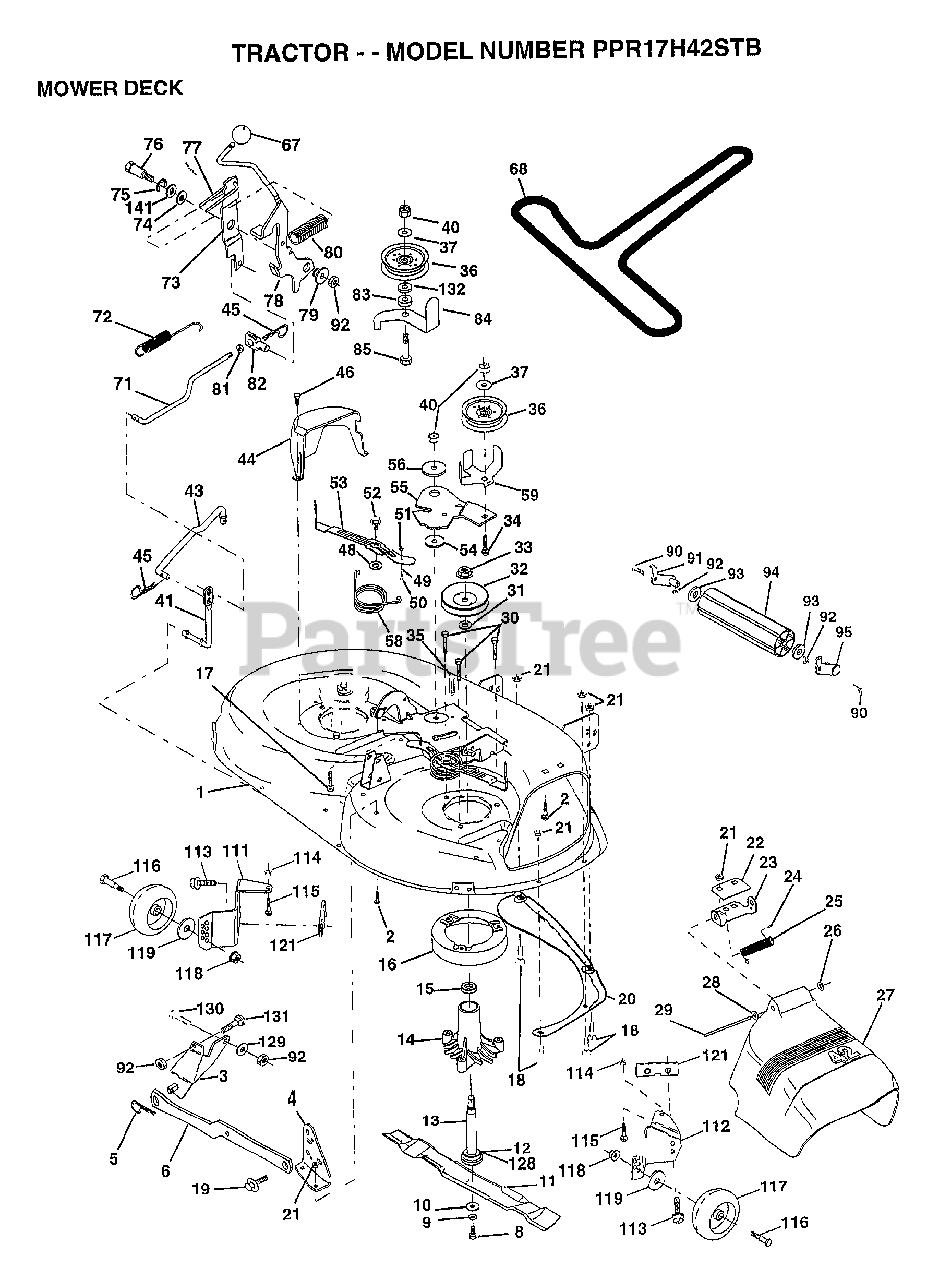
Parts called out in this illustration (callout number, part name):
1	"HOUSING ASSY.42"""
2	BOLT
3	BRKT ASM SWAY BAR
4	BRKT DECK SW BAR
8	BLADE BOLT
10	WASHER.HARD.BLADE
11	"BLADE.42"" HIPERF"
12	BEARING.BALL
14	HSG ASM MANDREL
15	BEARING
16	STRIPPER RND MWR
17	BOLT RDHD 3/8-16
18	BOLT
19	BOLT SHD 5/16-18
20	BAFFLE VORTEX 42
22	STIFFENER BRKT
23	DEFLECTOR BRKT
24	CAP-SLEEVE LT
25	SPRING TORSION
26	NUT PUSH M
27	DEFLECTOR.SHIELD
28	WASHER
29	HINGE ROD
30	"SCREW-THD ROLL,WA"
31	WASHER
32	PULLEY.MANDREL.42
34	BOLT
35	XMAS TREE FASTNER
36	FLAT IDLER PULLEY
37	WASHER
41	PIVOT ROD
43	ROD CLUTCH W/NIBS
44	GUARD MAND LH BLK
45	RETAINER M
46	SCREW.1/4-20X5/8
48	HARD SMALL WASHER
49	ROLLER ASM-CAM
50	SHOULDER BOLT
51	LOCKNUT
52	BOLT.SHLD.5/16-18
53	BRAKE PAD ARM ASM
54	HARDENED WASHER
55	ARM-IDLER
56	SPACER RETAINER
58	SPRING TORSN BRAK
59	GUARD IDLER TUV
67	KNOB.RD.7/16-14
68	BELT.V.T-PATH
71	ROD CLUTCH 38/42
72	RETURN SPRING
73	CLUTCH ARM SECOND
74	WASHER
75	RING
76	SHOULDER BOLT
77	SPRING KEEPER
78	LEVER.ASM.CLUTCH
79	BUSHING
80	SPRING.CLUTCH.MWR
81	NUT
82	TRUNION ADJ
83	WASHER
84	"KEEPER-BELT,FIXED"
85	BOLT
90	BOLT
92	NUT
93	WASHER
111	BRACKET.GWHL.LH.
112	BRACKET.GWHL.RH.
113	SCREW
116	BOLT M
117	WHEEL.GUAGE
118	LOCKNUT
119	WASHER
121	BRACKET.EXTRD.GWL
128	WASHER.FELT.
132	WASHER GT
141	WASHER .T
